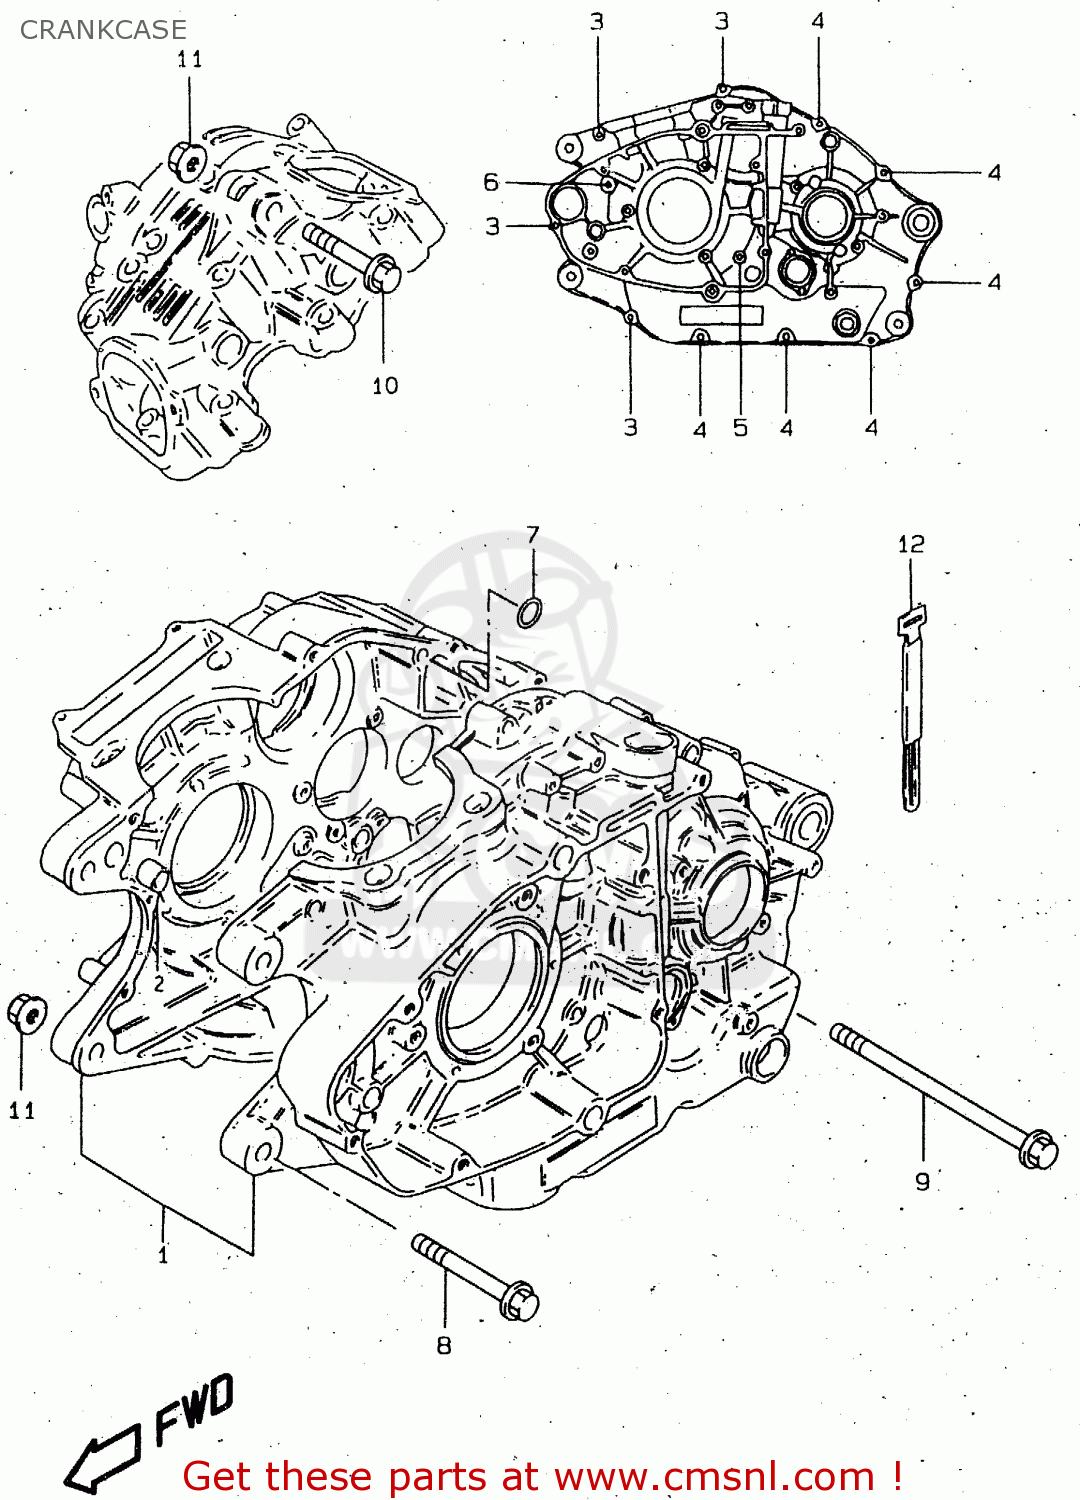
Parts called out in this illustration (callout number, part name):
1	CRANKCASE SET
2	PIN
3	BOLT
4	BOLT
5	BOLT
6	BOLT
7	O RING(D:1.9,ID:8.6)
8	BOLT(8X67)
9	BOLT(8X100)
10	BOLT(8X50)
11	NUT
12	CLAMP,AIR CLEANER DRAIN TUBE
